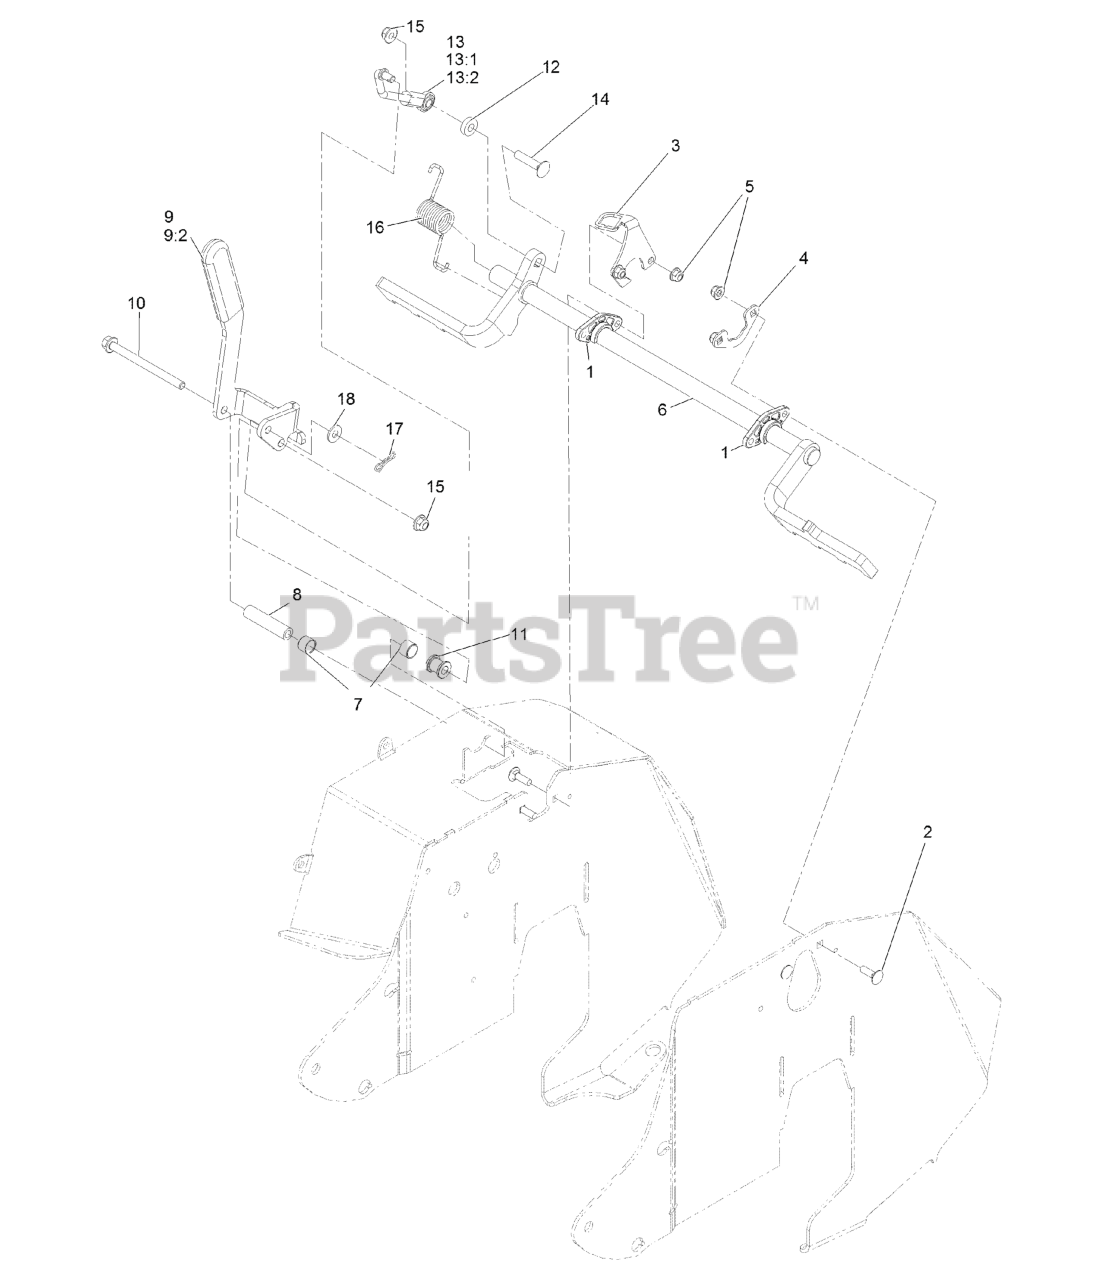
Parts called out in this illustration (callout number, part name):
1	BUSHING-FLANGE
2	BOLT-CARR
3	BRACKET-SWITCH
4	SUPPORT, BEARING
5	NUT-HF, NI
6	WLD-BRAKE SHAFT 32/36
7	SLEEVE-BUSHING
8	BUSHING-PIVOT
9	ASM-BRAKE LEVER WITH GRIP
9:2	GRIP-LEVER
10	SCREW-HF
11	SPACER-.39IDX.88ODX.88L
12	SPACER
13	ASM-BRAKE LINK
13:1	JOINT-BALL, END
13:2	ROD-BRAKE
14	SCREW-CARR
15	NUT-HF, NI
16	SPRING-TORSION
17	PIN-COTTER, LOCKING
18	WASHER-FLAT
